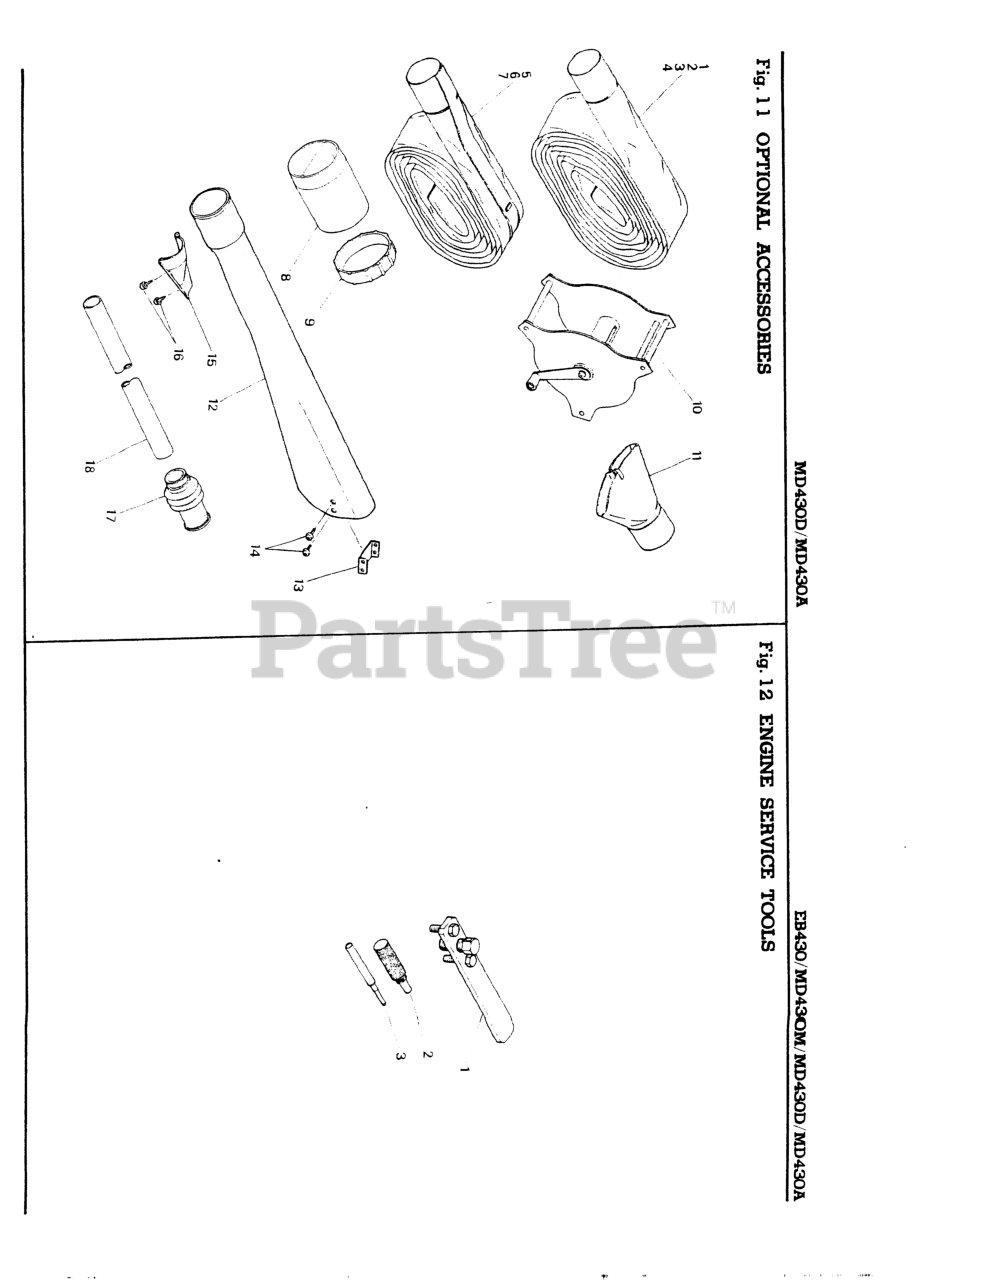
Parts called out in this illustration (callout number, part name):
1	JET HOSE
2	JET HOSE
3	JET HOSE
4	JET HOSE
5	JET HOSE
6	JET HOSE
7	JET HOSE
8	ADAPTER, JET HOSE
10	REEL ASSY
12	SPRAY PIPE ASSY
18	TUBE (NO LONGER AVAILABLE)
